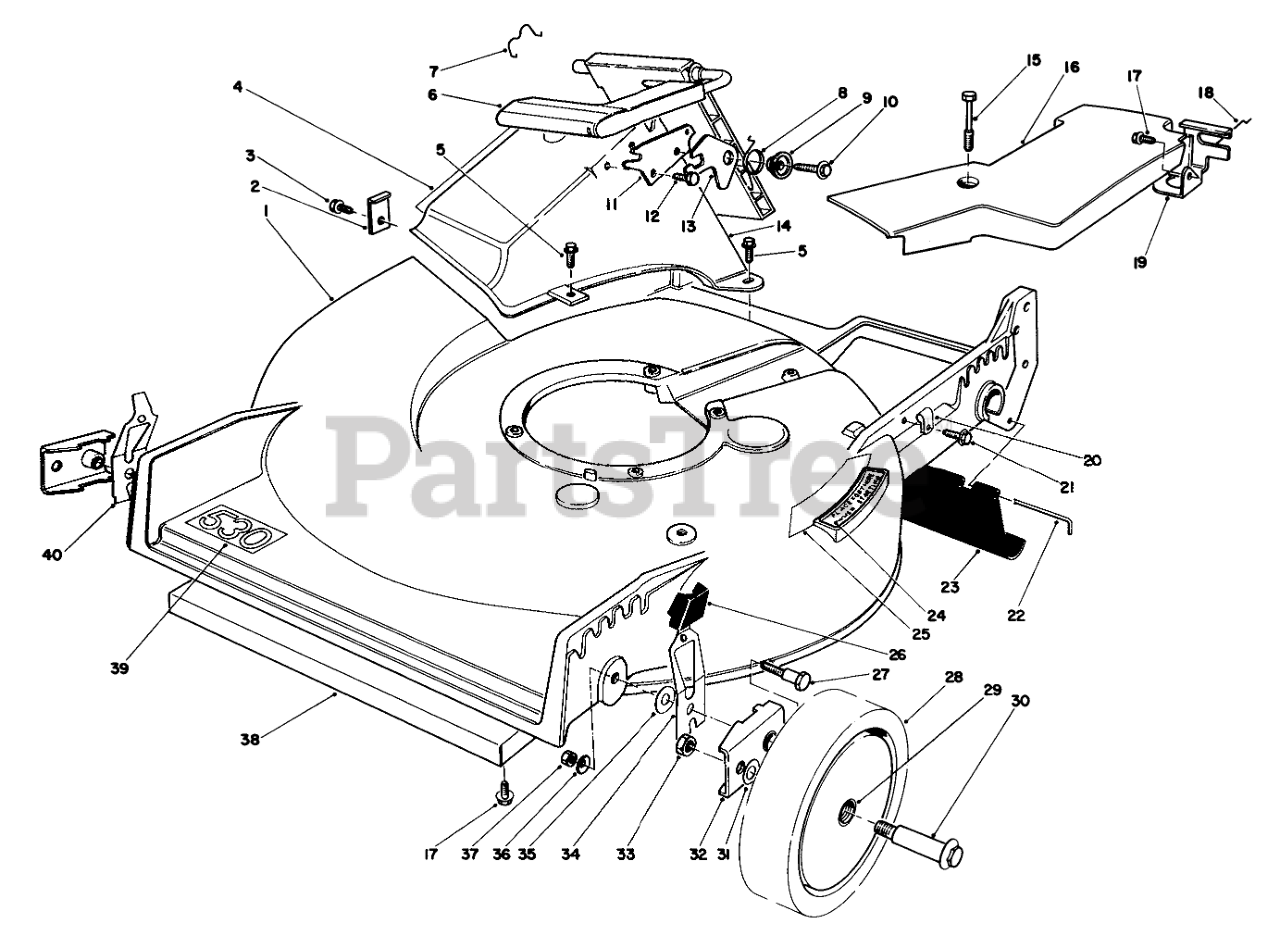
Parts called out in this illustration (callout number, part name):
1	21 SP RB HSG/DECAL
2	TUNNEL CLIP
3	SCREW
4	ATTENTION DECAL
5	SCREW-HWH
6	Discharge Door Assembly
7	DOOR RET SPRING
8	TORSION SPRING
9	DOOR SPACER
10	SCREW-HWH
11	DOOR LATCH PLATE
12	SCREW-PLASTITE
13	Latch-Door
14	Tunnel Discharge
15	SCREW-HHFTF
16	Cover-Belt
17	SCREW-HWHTF
18	RETAINER-CABLE
19	Bracket-Traction Adj.
20	CLAMP-CABLE
21	SCREW
22	ROD-SHIELD
23	SHIELD-TRAILING
24	STEP PAD DECAL
25	Decal-Place Foot Here
26	KNOB-ARM
27	PIVOT SCREW
28	Wheel & Tire Assy. (Incl. Ref. #29)
29	BUSHING
30	WHEEL BOLT
31	WASHER
32	HP PIVOT ARM ASM
33	NUT-LOCK
34	L. HP SPRING ARM ASM
35	WASHER-PIVOT
36	WASHER-BELLEVILLE
37	NUT-LOCK, NI
38	Shield-front
39	Decal-530
40	R HP SPRING ARM ASM
